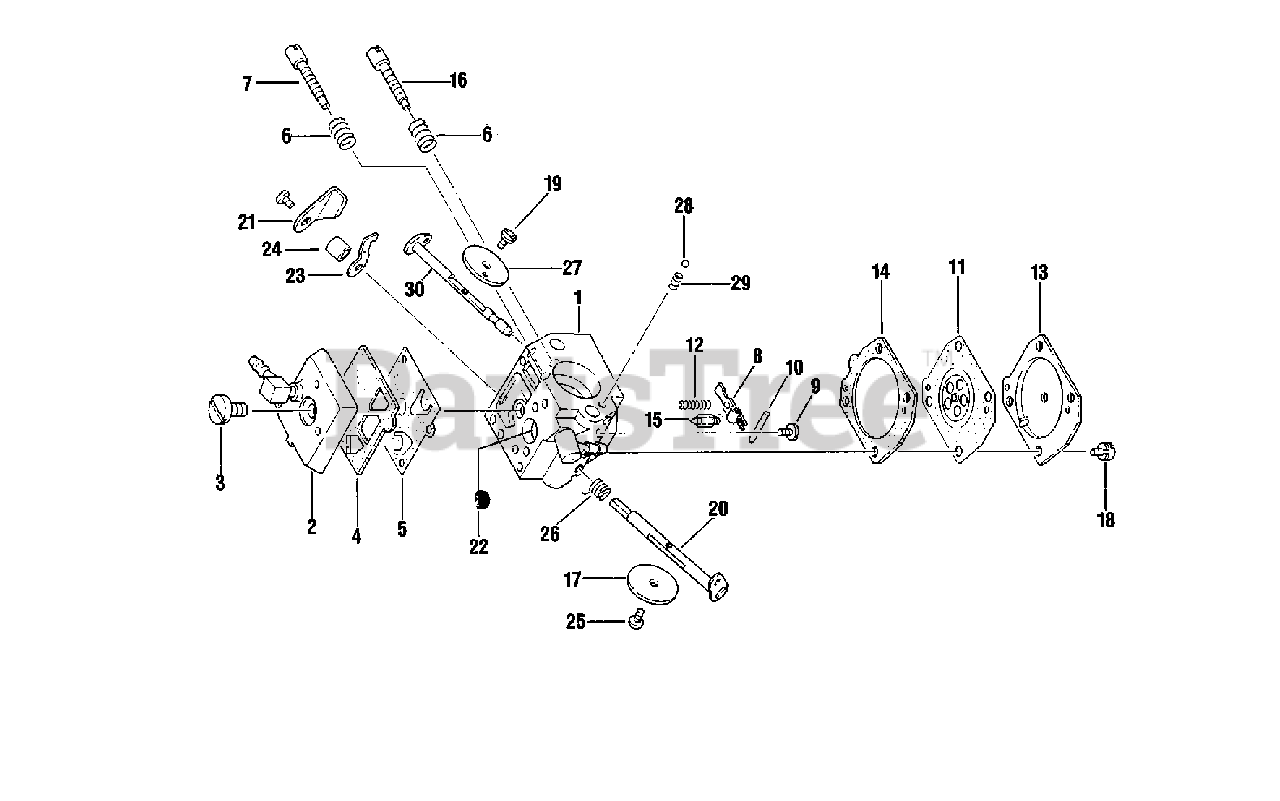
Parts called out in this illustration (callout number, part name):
1	BODY, CARBURETOR
2	COVER, PUMP
3	SCREW
4	GASKET, PUMP
5	DIAPHRAGM, PUMP
6	SPRING
7	NEEDLE - LOW SPEED
8	LEVER, METERING
9	SCREW, METERING LEVER PIN
9	SCREW
10	PIN, METERING LEVER
10	PIN
11	DIAPHRAGM, METERING
11	DIAPHRAGM ASSY
12	SPRING, METERING LEVER
12	SPRING
13	COVER, DIAPHRAGM
14	GASKET, METERING
14	GASKET, DIAPHRAGM
15	VALVE, INLET NEEDLE
15	VALVE
16	NEEDLE - HIGH SPEED
17	VALVE, THROTTLE
18	SCREW
19	SCREW
20	SHAFT, THROTTLE
21	TRIGGER, THROTTLE
22	STRAINER
23	STOP, THROTTLE
24	SPACER
25	SCREW
26	SPRING, THROTTLE RETURN
27	VALVE, CHOKE
28	BALL, CHOKE
29	SPRING, CHOKE
30	SHAFT, CHOKE
